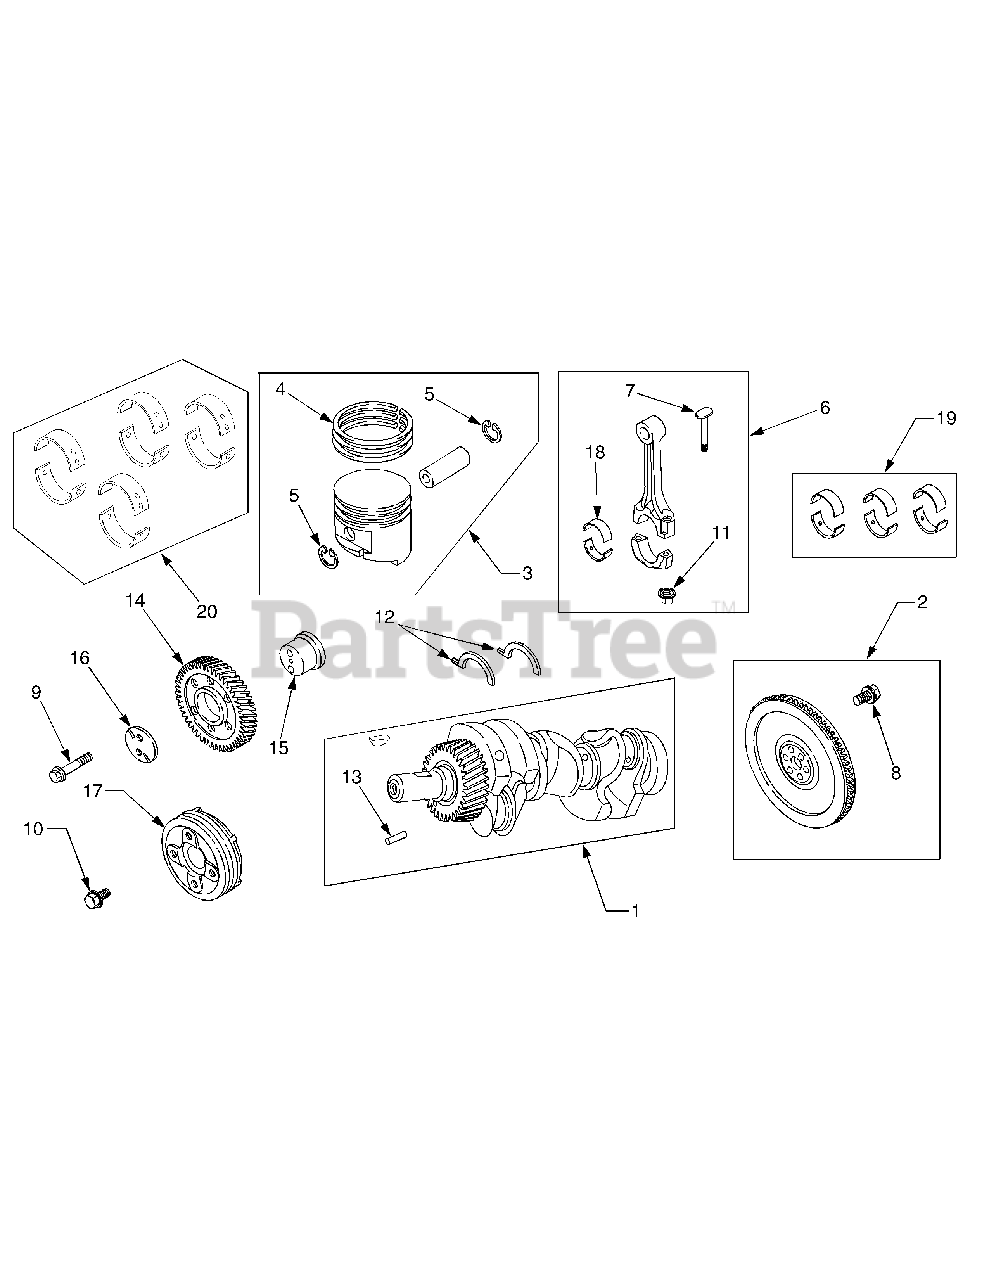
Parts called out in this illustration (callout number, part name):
1	Crankshaft
3	Piston Assembly, Standard
3	Piston Assembly, .010 Oversize ..
4	Ring Set, Standard
4	Ring Set, .010 Oversize
5	Lock Ring, Piston Pin
6	Rod, Connecting
7	Screw, Connecting Rod
8	Screw, Hex, 10mm
9	Screw, Hex, 8mm
10	Screw, Hex
12	Washer, Thrust, Standard
12	Washer, Thrust, .005 Oversize
13	Pin, Locating
14	Gear, Drive
15	Shaft, Gear
16	Plate, Idler Gear
17	Pulley, Crankshaft
18	Bearing, Rod Standard
19	Bearing Set, Rod Standard
19	Bearing Set, Rod, .010 Undersize
20	Bearing Set, Main Standard
20	Bearing Set, Main, .010 Undersize
